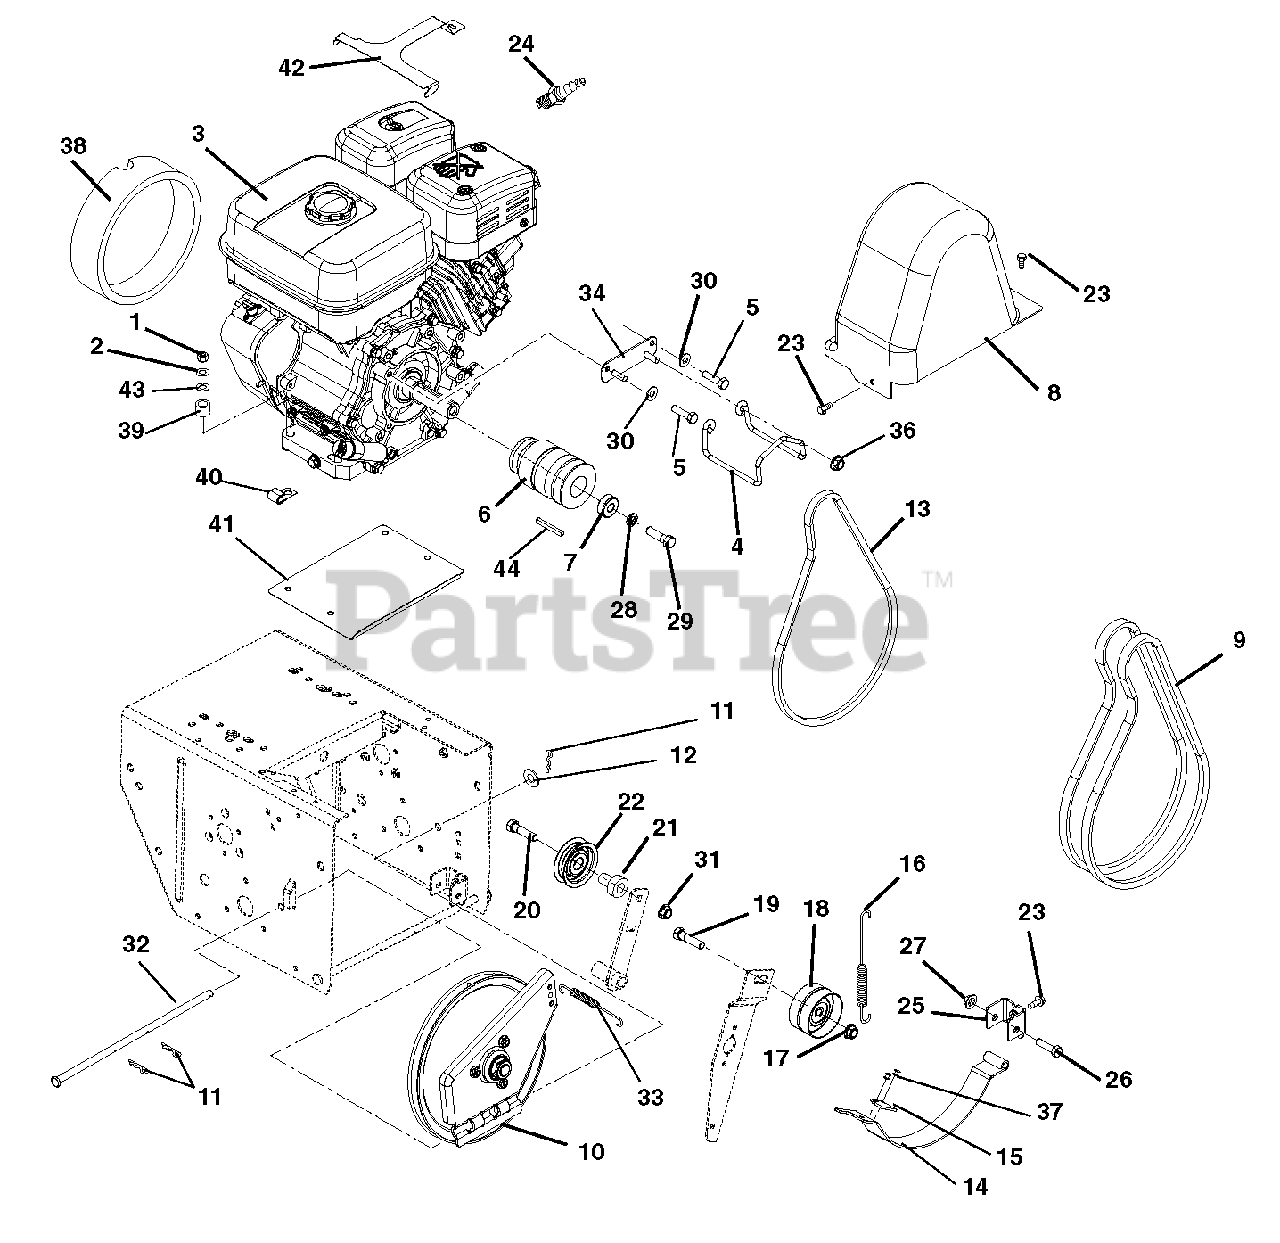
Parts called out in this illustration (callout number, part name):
1	Nut, Hex .31-18
2	Washer, Lock .312 x .097
3	Engine, Subaru EX27 All-Season
4	Belt Finger
5	Bolt, Hex .31-24 x .75 Grade 5
6	Sheave, Subaru EX27
7	Bushing, Spacer .47 x 1.25 x .50
8	Cover, Belt
9	V-Belt, Set
10	Plate, Deep Swing Assembly
11	Hair Pin
12	Washer, Flat Steel .406 x .812 x .065
13	V-Belt, 3L-Raw Edge
14	Arm, Brake Attachment
15	Pad, Brake
16	Spring, Tension
17	Nut, Locking Top Flange .38-16
18	Idler, Flat 2.75"
19	Bolt, Hex .38-16 x 1.50 Grade 5
20	Bolt, Hex .31-18 x 1.25 Grade 5
21	Spacer, Bearing
22	Idler
23	Screw, Tapping .25-20 x .50 Hex Washer Hea
24	Plug, Spark
25	Pivot, Brake
26	Bolt, Hex .31-18 x 2.00 Grade 5
27	Nut, Locking-Top-Flange .31-18
28	Washer, Locking .44 x .109 Regular
29	Bolt, Hex .44-20 x 1.50 Grade 5
30	Washer, Locking .312 x .097 Heavy
31	Nut, Locking-Top-Flange .31-18
32	Rod, Pivot
33	Spring, Tension
34	Plate, Belt Finger Mount
35	Washer, Flat-Steel .536 x 1.07 x .109
36	Nut, Locking-Top-Flange .31-18
37	Rivet, Pop .187
38	Foam Cover, Recoil Subaru
39	Bushing, Sleeve .325 x .400 x .795
41	Baffle, Water-Pro Series
42	Guard, Snow Subaru
43	Washer, Flat-Steel .38 x .875 x .083
44	Key .25 x .25 x 2.25
